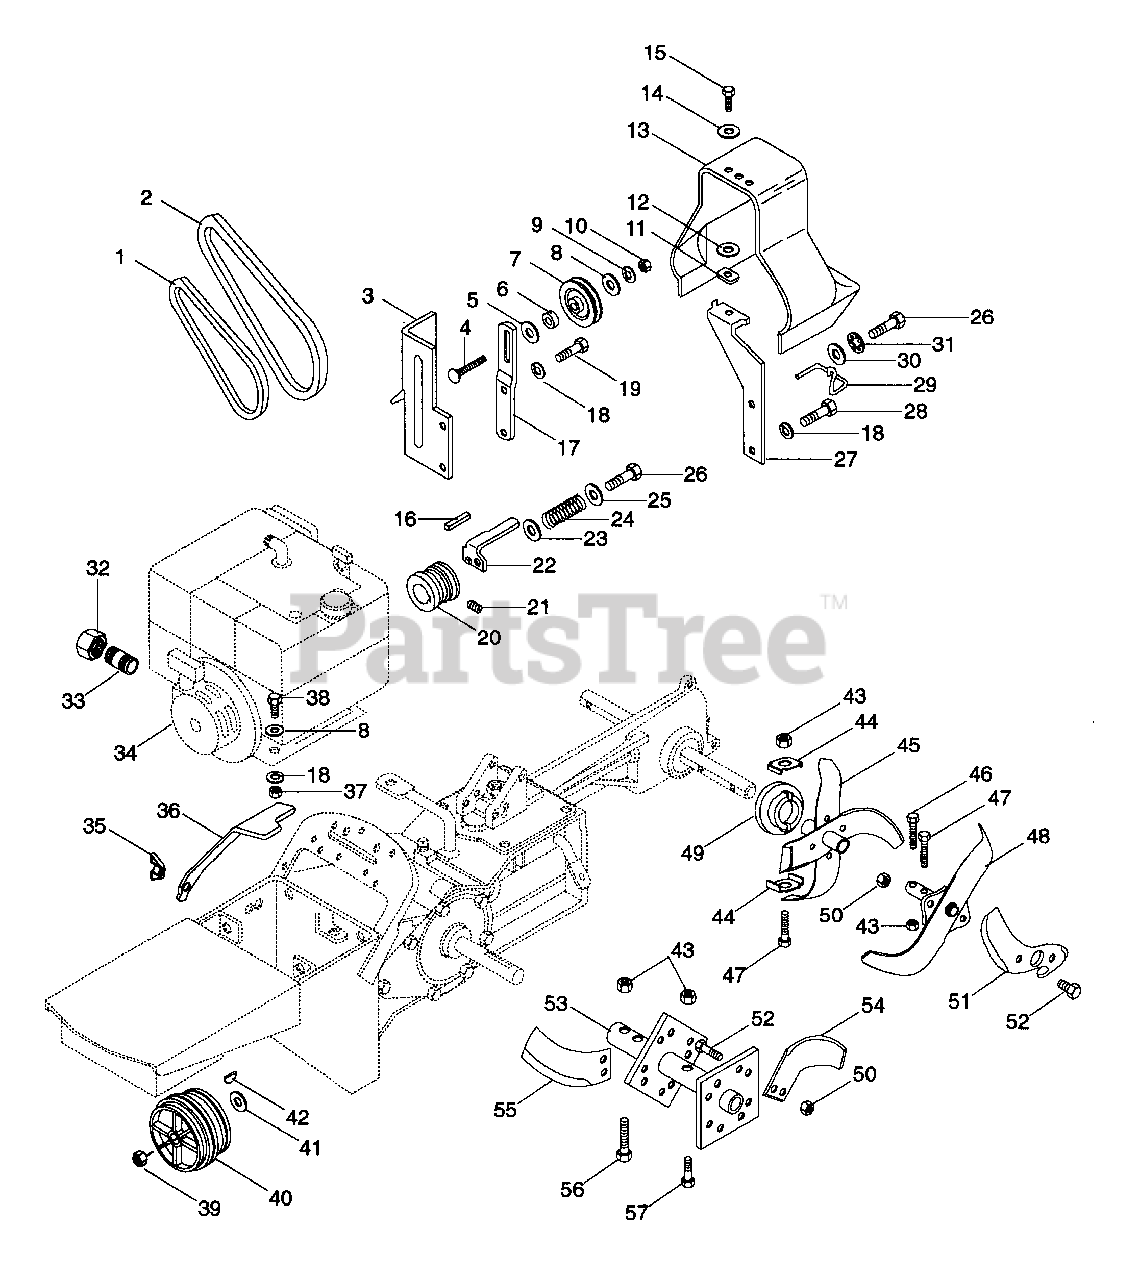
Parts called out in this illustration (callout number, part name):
1	V-BELT, 4L-WRAPPED
1	V-BELT, SAE 380-RAW EDGE (SET)
2	V-BELT, 3L-COGGED
3	HEAT SHIELD
4	BLT-RDHDSQNK .31-18X1.75 SHTPL
4	BLT-RDHDSQNK .31-18X1.38SHT PL
5	WSHR-FL-STL .380X.875X.179 PL
6	BEARING SPACER
6	SPCR, BRG .315X.50X.688X.281
7	IDLER
8	WSHR-FL-STL .38X.875X.083 PL
9	WSHR-LK .312X.097 PL HVY
10	NUT-HEX .312-18
11	NUT-SPEED U-TYPE .250-20
12	NUT-RETNR
13	BELT GUARD W/DECALS
14	WSHR-FL-STL .250X.562X.049 PL
15	BLT-HEX .25-20X.50 PL GR2
16	KEY-SQ .188X1.0X.188 SAE 8630
16	KEY-SQ .25 X 1.25 X .25 SAE
17	REVERSE IDLER BRACKET
18	WSHR-LK .312X.097 PL HVY
18	WSHR-LK .375X.115 HVY PL
19	BLT-HEX .31-24X.75 PL GR5
19	BLT-HEX .38-16X.75 PL GR2
20	ENGINE SHEAVE
21	SCR-SET .25-20X.25 SKHCUPNY OH
21	SCR-SET .32-18X.38 SKHCUPNL OH
22	BELT FINGER
23	WSHR-FL-STL .406X1.125X.125 PL
24	SG-COMP .125X.68X1.62
25	WSHR-FL-STL.406X.812X.065PL
26	BLT-HEX .31-24X1.00 PL GR5
26	BLT-HEX .38-16X2.00 PL GR2
27	BELT COVER BRACKET
28	BLT-HEX .31-24X.50 GR5
28	BLT-HEX .38-16X.63 PL GR2
29	FORWARD BELT FINGER
29	BELT FINGER
30	WSHR-FL-STL .323X.625X.062 PL
31	WSHR-LK-INT .313X.030 PL
32	HEX PIPE CAP 1/2 NPT
33	MALE PIPE NIPPLE 1/2 NPT
34	5 HP TEC 5020
34	7 HP TEC 7020
34	8 HP KOHLER #301515
34	6 HP TEC
35	NUT-WING W/INSERT .312 - 18
36	BELT FINGER
37	NUT-HEX .312-18
37	NUT-HEX .375-16
38	BLT-HEX .31-18X1.00 PL GR 2
38	BLT-HEX .38-16X1.25 PL GR 2
39	NUT-LK-CTR .75-16 PL
40	DRIVE SHEAVE
41	WSHR-FL-STL .765X1.250X.062
42	KEY-FTHR .188X1.25X.187 SAE
43	NUT-LK-CTR .375-16 GR A PL
43	NUT-LK TOP .375-16 GR C YWZC
45	RH INNER TINE SPOOL
45	LH INNER TINE SPOOL
46	BLT-HEX .38-16X1.75 PL GR2
47	BLT-HEX .38-16X2.00 PL GR2
48	LH OUTER TINE SPOOL
48	RH OUTER TINE SPOOL
49	DUST CAP
50	NUT-LK-TOP .437-14 GR C PL
51	TURBO-TINE
52	BLT-HEX .44-14X1.00 GR5
53	INNER TINE HUB
54	L KNIFE TINE
55	R KNIFE TINE
56	BLT-HEX .38-16X2.75 GR8
57	BLT-HEX .38-16X2.00 GR8
